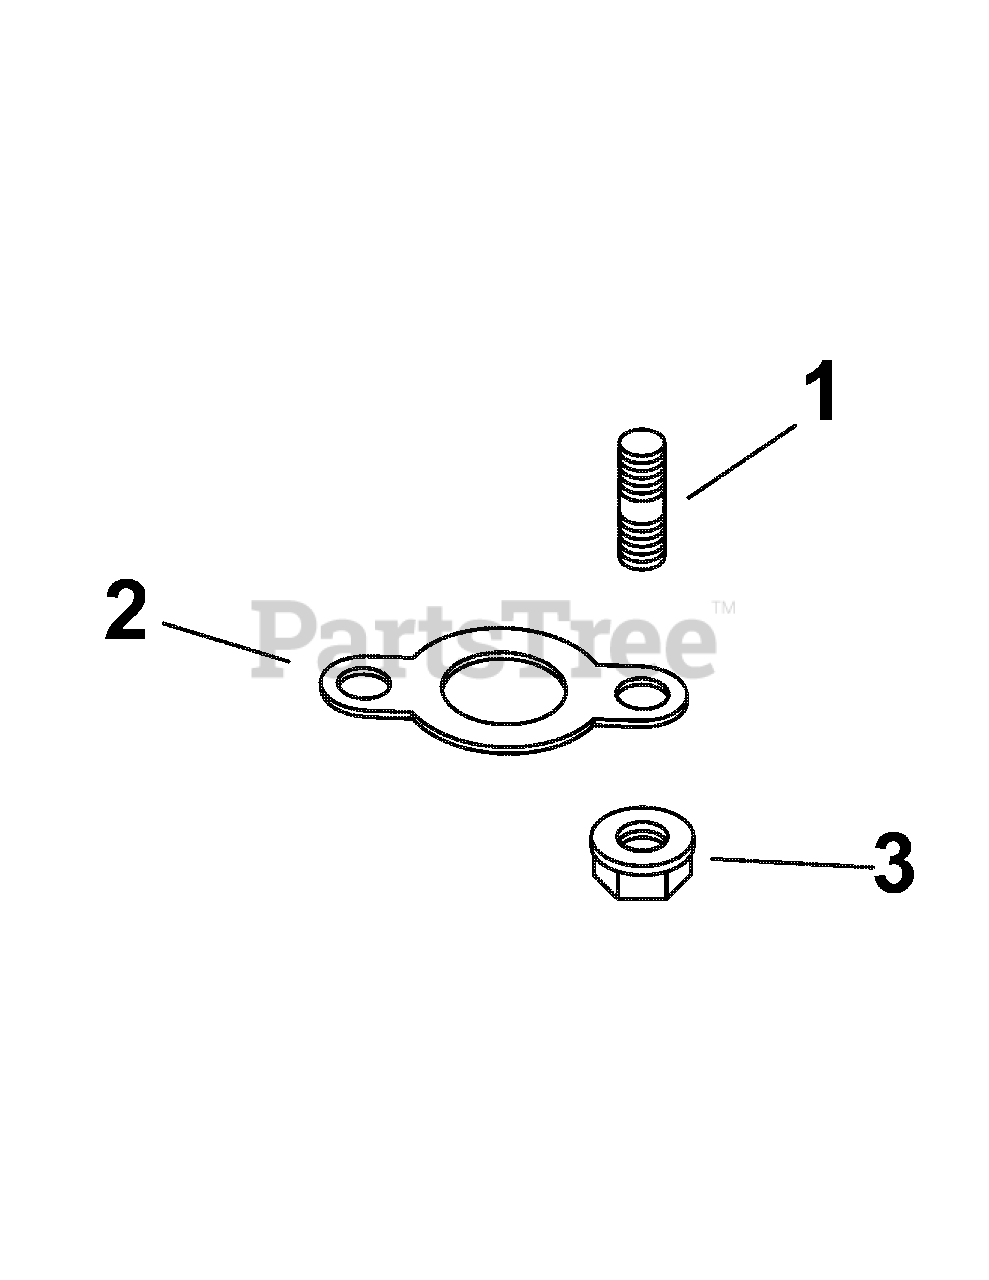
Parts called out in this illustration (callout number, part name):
1	Stud, M8 x 1.25 x 33
2	Gasket, Exhaust
3	Nut, Flg M8 x 1.25
